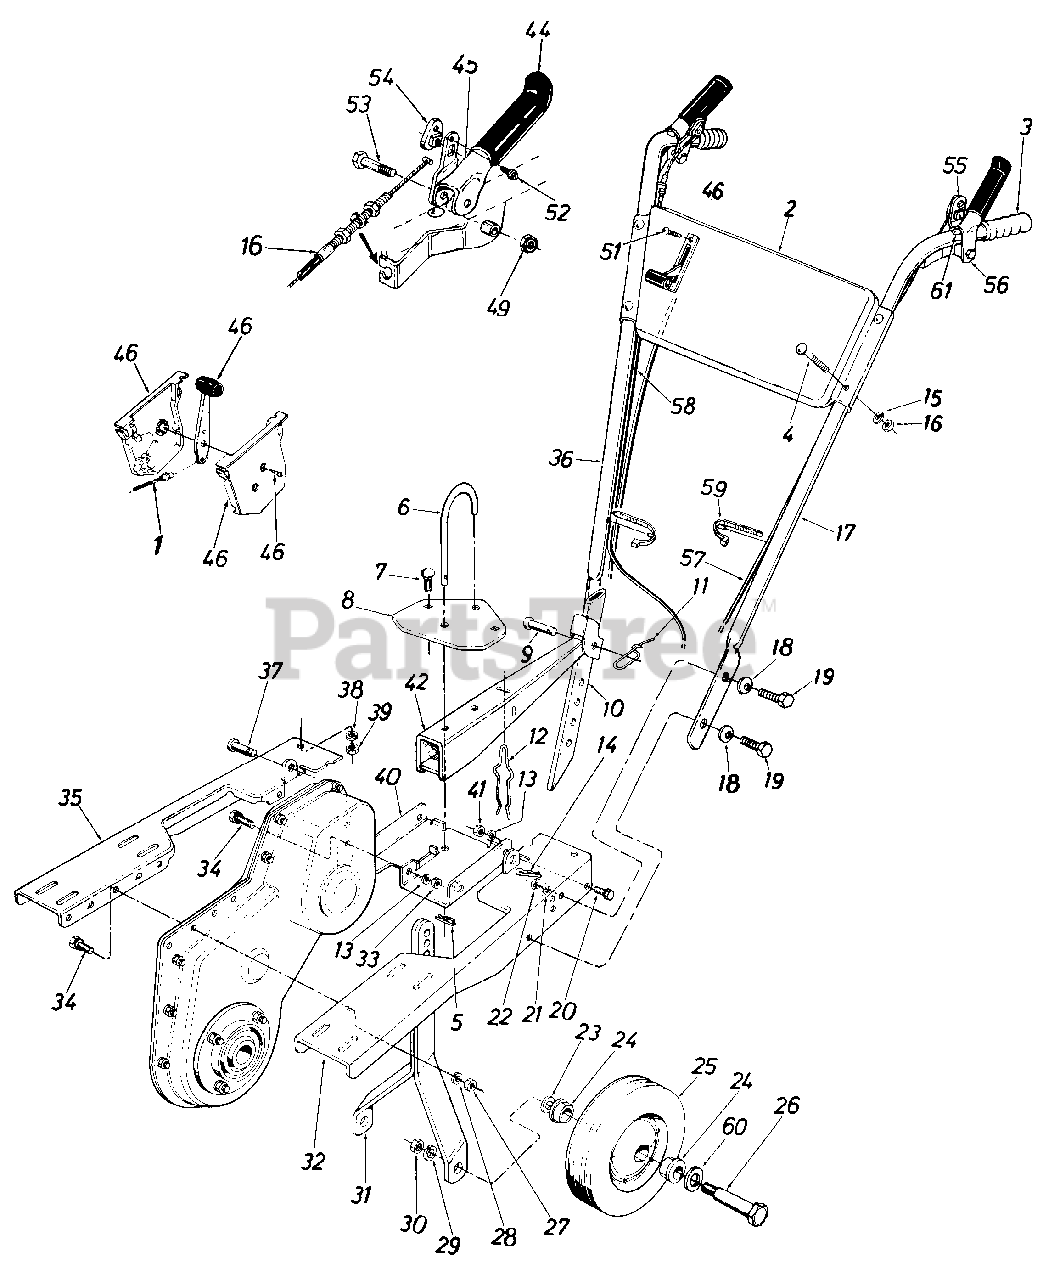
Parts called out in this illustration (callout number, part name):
1	Throttle Control Wire-35"
2	Handle Panel Ass'y.
3	Handle Grip
4	Carriage Bolt 5/16-18 x 1.75"
5	Internal Coter Pin
6	"U"-Clevis Pin .500" Dia.
7	Carriage Bolt 5/16-18 x .75"
8	"U"-Channel Plate
9	Clevis Pin 1/2" Dia.
10	Depth Bar
11	Spring Pin
12	Depth Bar Spring
13	L-Wash. 5/16" I.D.
14	Internal Coter Pin
15	L-Wash. 5/16" I.D.
16	Hex Nut 5/16-18 Thd.
17	Handle-L.H.
18	Belleville Wash. 3/8" I.D.
19	Hex Bolt 3/8-16 x 1.00" Lg.
20	Hex Bolt 5/16-18 x .75" Lg.
21	L-Wash. 3/8" I.D.
22	Hex Nut 3/8-16 Thd.
23	Belleville Wash. .505 I.D. x 1.00" O.D.
24	Fl. Bearing w/Flats .631 I.D.
25	Wheel Ass'y. Comp. 10 x 1.75
26	Shoulder Bolt .625" Dia. x 2.75" Lg.
27	Hex Nut 5/16-18 Thd.
28	L-Wash. 5/16" I.D.
29	L-Wash. 1/2" I.D.
30	Hex Ins. L-Nut 1/2-20 Thd.
31	Wheel Bracket Ass'y.
32	Engine"U"-Channel Ass'y.L. H .
33	Hex Nut 5/16-18 Thd.
34	Hex Sems Bolt 5/16-18 x 1.00" Lg.
35	Engine"U"-Channel Ass'y. R.H.
36	Handle-R.H.
37	Clevis Pin .375" Dia.
38	L-Wash. 5/16" I.D.
39	Hex Nut 5/16-18 Thd.
40	"U"-Channel Bracket Ass'y.
41	Hex Nut 5/16-18 Thd.
42	Tailpiece Ass'y.
44	Clutch Vinyl Grip
45	Clutch Grip Ass'y.R.H.
46	Throttle Control Box Ass'y.
49	Hex Ins. L-Nut 3/8-24 Thd.
51	Self-Tap Scr. #10 x 1/2" Lg.
52	Self-Tap Scr. #10 x .44" Lg.
53	Hex Bolt 3/8-24 x 2.0" Lg.
54	Barrel Cable Hold-Down-R.H.
55	Barrel Cable Hold-Down-L.H.
56	Clutch Grip Ass'y.L.H.
57	Control Cable
58	Control Cable
59	Cable Tie
60	Fl-Wash. .640 I.D. x 1.24"
61	Plug
